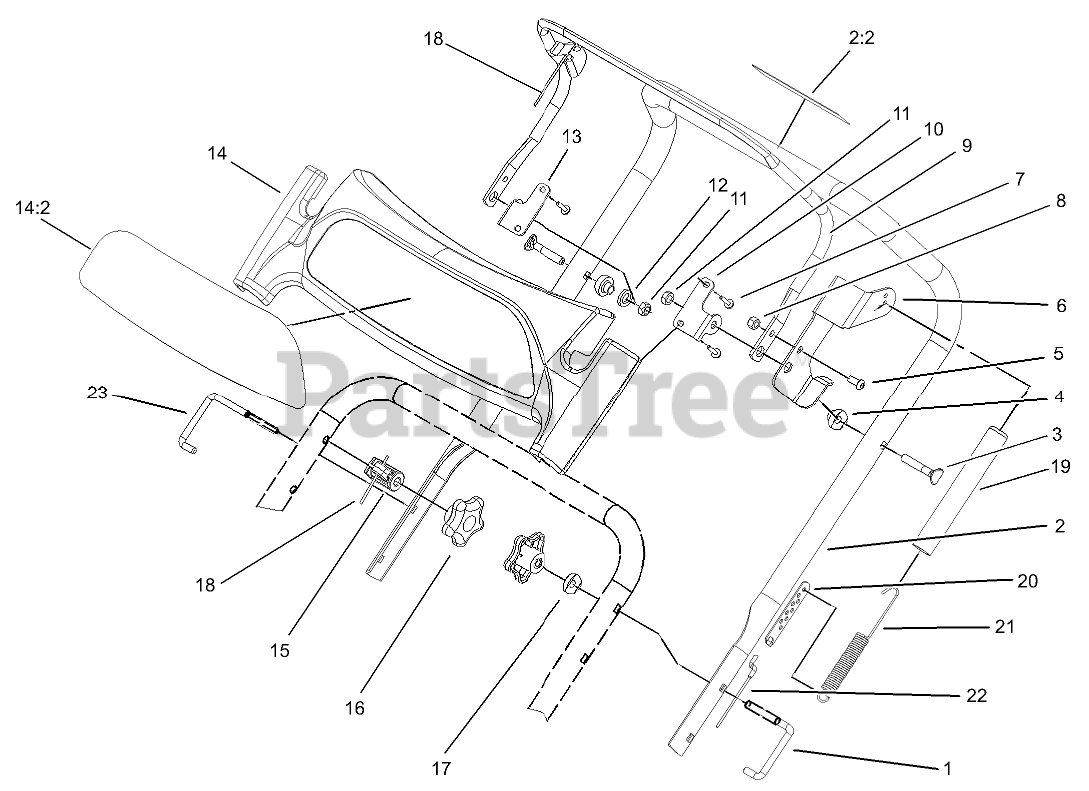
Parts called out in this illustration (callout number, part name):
1	LOCK-HANDLE
2	HANDLE-UPPER W/DECAL
2:2	DECAL-DRIVE, ROTOR
3	SCREW-HANDLE
4	SPACER-BAR, CONTROL
5	SCREW-HSBH
6	ARM-CLUTCH, HANDLE
7	SCREW-HWH
8	NUT-LOCK, NI
9	BAR-CONTROL
10	BRACKET-PANEL, LH
11	NUT-LOCK, NI
12	WASHER
13	BRACKET-PANEL, RH
14	DISPLAY HANDLE PANEL ASM
14:2	Decal-Display, Handle
15	GUIDE-Cable, PIVOT
16	KNOB-HANDLE
17	WASHER-CURVED
18	CABLE-PIVOT
19	COVER-SPRING
20	ADJUSTER-CABLE, CLUTCH
21	SPRING-CABLE
22	CABLE-CLUTCH
23	LOCK-HANDLE, RH
